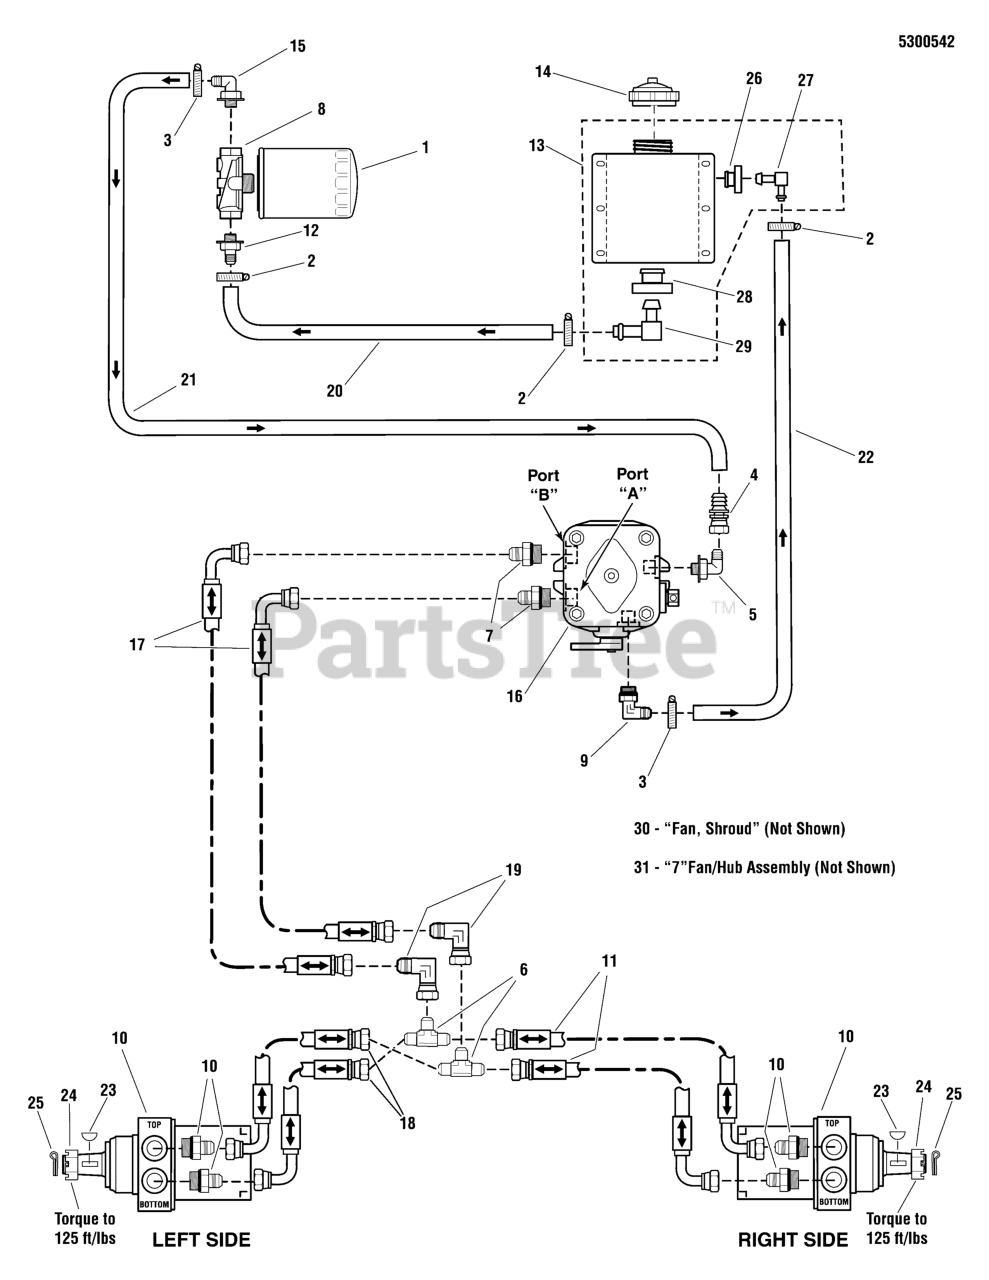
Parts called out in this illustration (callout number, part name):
1	FILTER, OIL
2	CLAMP, #10 HOSE, STAINLESS
3	CLAMP, #6 HOSE, STAINLESS
4	FITTING, STR JIC TO HOSE #8
5	FITTING, #8 JIC - #8 O-RING, 90 DEG.
6	FITTING T JIC #8
7	ADAPTER, HYD.
8	FILTER HEAD, HYDRAULIC
9	ADAPTER, 90 DEG, 9/16-3/8 BARB
11	HOSE ASSEMBLY, 11.5" 90-STR
12	FITTING, STRAIGHT, HYD #12618
13	TANK, HYDRAULIC, ASSEMBLY
14	CAP, HYDRAULIC
15	FITTING, 9/16 O-RING-1/2" HOSE, 90 DEG
16	* PUMP, HYDRO-GEAR, BDP-16CC
17	HOSE ASSEMBLY, 19.63" 90-STR
18	HOSE ASSEMBLY, (25)
19	FITTING, 90 DEG. #8 JIC M - #8 JIC F
20	HOSE, 5/8" PUSH-ON, 3.00"
21	HOSE, 1/2" PUSH-ON, 17.50"
22	HOSE, 3/8" PUSH-LOCK, 15.50"
23	KEY
24	NUT, CASTLE
25	PIN, COTTER
26	BUSHING-FUEL TANK RED RUBBER
27	FITTING, ELBOW, 3/8"
28	GROMMET
29	FITTING, ELBOW, 5/8"
30	FAN SHROUD
31	7" FAN / HUB ASSEMBLY
